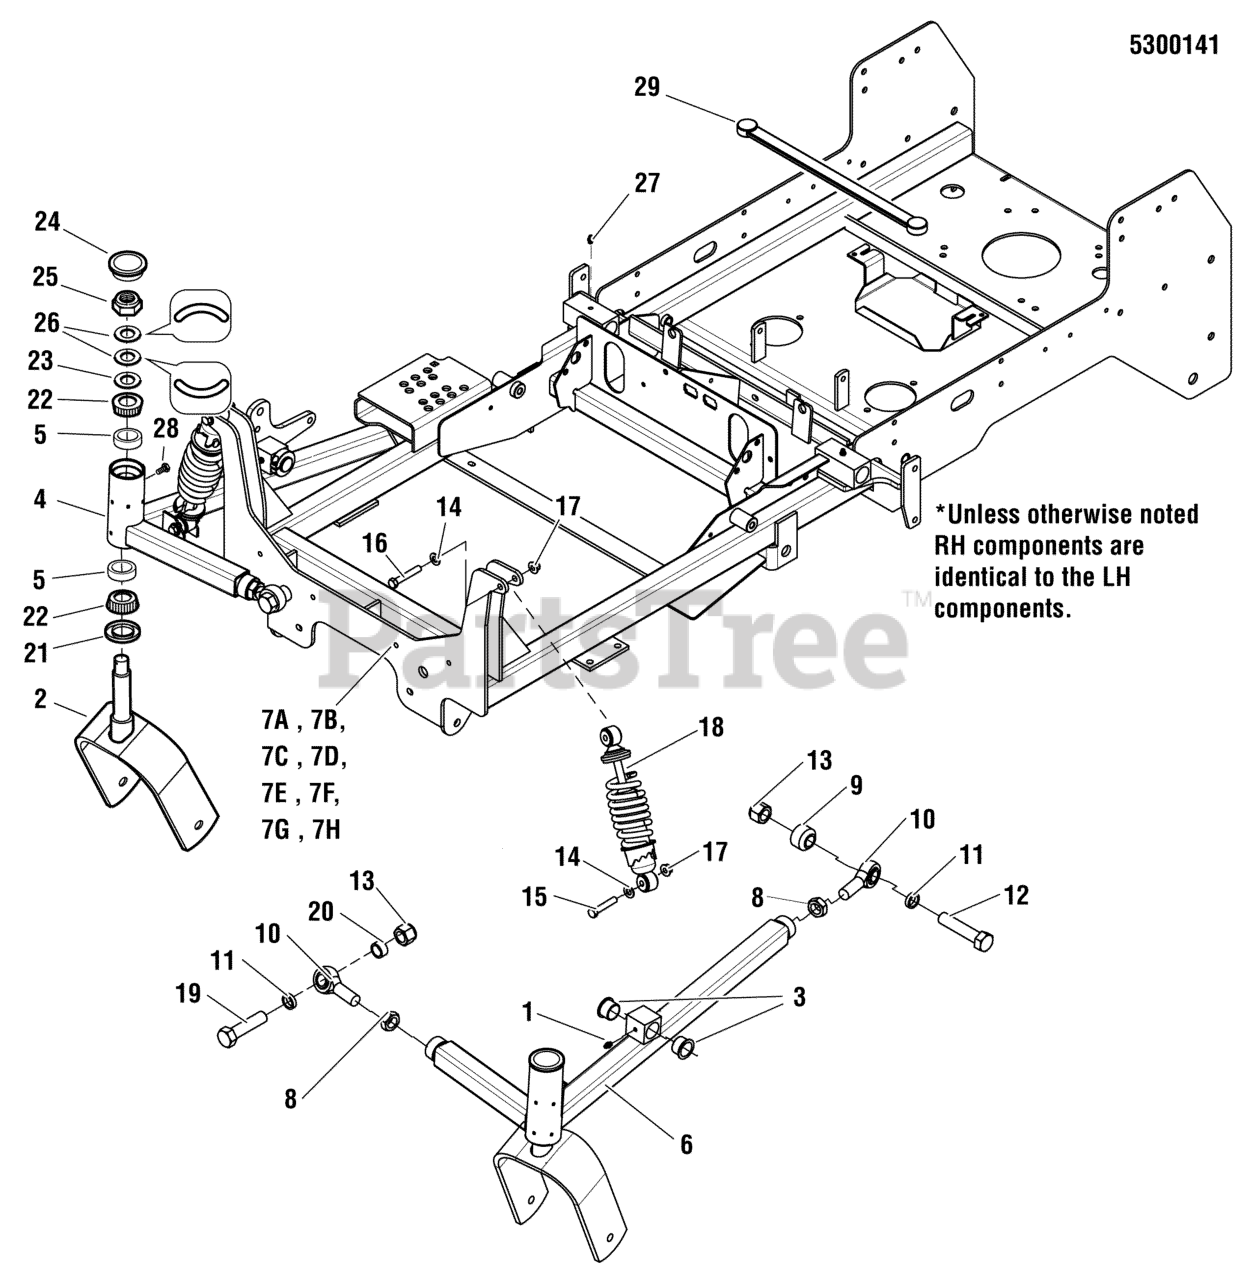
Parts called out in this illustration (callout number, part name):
1	GREASE FITTING, 1/4-28 STRAIGHT
2	WELD, CASTER YOKE - RED
3	BUSHING, 1.00X1.13X.75, PLA
4	WELD, FRONT A-ARM - RH -RED
5	BEARING CUP
6	WELD, FRONT A-ARM - LH -RED
8	NUT, HEX JAM, 3/4-16
9	SPACER, .75 X 1.50 X 1.00
10	BALL JOINT, 3/4-16 MALE
11	SPACER, .76 X 1.00 X .25
12	BOLT, 3/4-16 X 3-1/2" YZ GD5
13	NUT, 3/4-16 HEX NYLON LOCK
14	WASHER, 3/8 SAE
15	BOLT, 3/8-16 X 2, GD5, CZ
16	BOLT, 3/8-16 X 2-1/4" GD5 CZ
17	NUT, 3/8-16 HEX NYLOCK FLANGE
18	SHOCK ABSORBER
19	BOLT, 3/4-16 X 3" YZ GD5
20	SPACER, .76 X 1.00 X .50
21	SEAL, GREASE
22	BEARING, TAPPERD ROLLER, 1"
23	WASHER, 3/4 SAE
24	CAP, GREASE, LOW PROFILE
25	NUT, 3/4-16, HEX JAM NYLON LOCK
26	BELLEVILLE WASHER, 1.500 X .755
27	GREASE FITTING, 1/4-28 45 DEGREE
28	BOLT, 1/4-28 X 1/2, GD5 YZ
29	STRAP-BLACK RUBB
